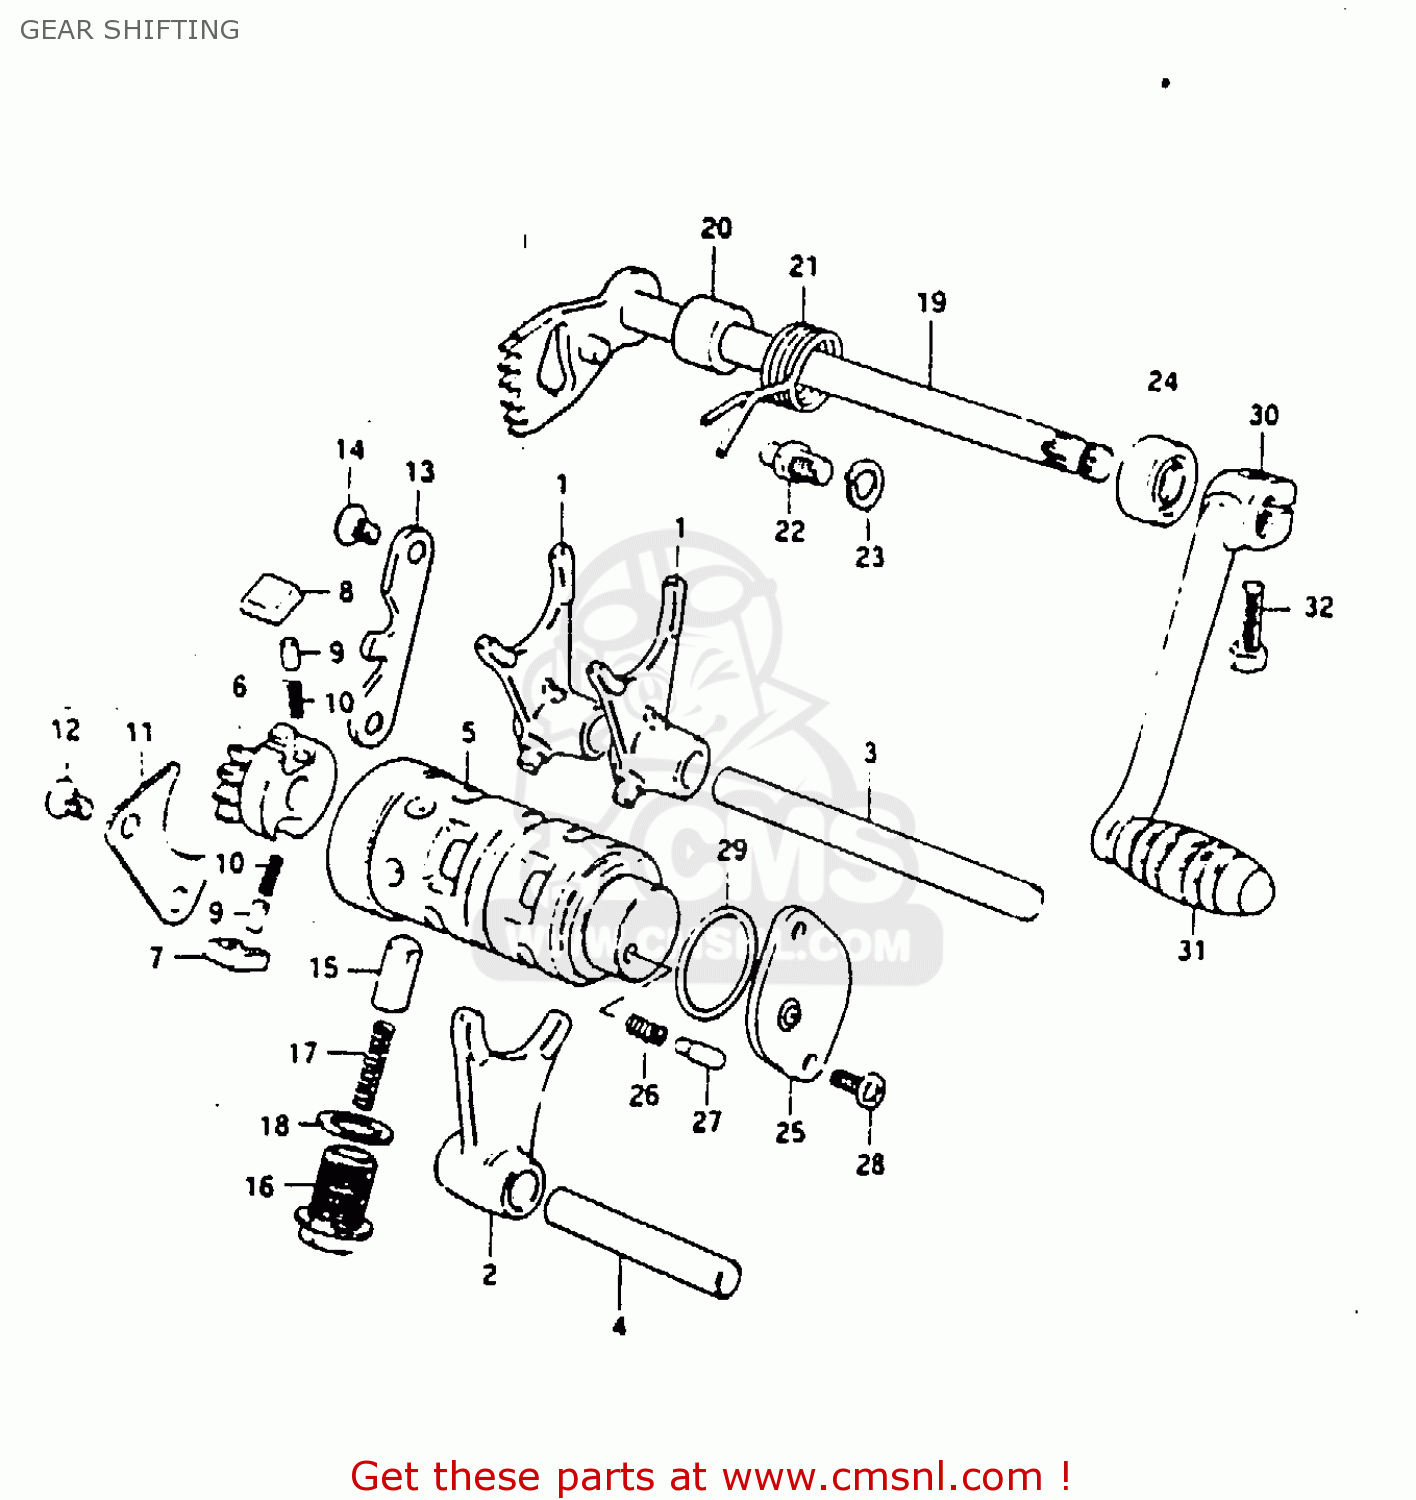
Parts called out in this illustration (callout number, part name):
1	FORK,GEAR SHIFT NO.1
2	FORK,GEAR SHIFT NO.2
3	SHAFT,GEAR SHIFT FORK
4	SHAFT,GEAR SHIFT FORK
5	CAM,GEAR SHIFT
6	GEAR,GEARSHIFT CAM DRIVE
7	PAWL,GEAR SHIFT NO.1
8	PAWL,GEAR SHIFT NO.2
9	PIN(5X8)
10	SPRING
11	LIFTER,GEAR SHIFT POLE
12	SCREW
13	GUIDE,GEAR SHIFT CAM
14	SCREW
15	STOPPER,GEAR SHIFTING
16	BOLT,GEAR SHAFT CAM STOPPER
17	SPRING
18	GASKET(14X19.2X2) (NAS)
19	SHAFT,GEAR SHIFT
20	SPACER(12X20X15.3)
21	SPRING
22	STOPPER,GEAR SHIFT CAM
23	WASHER,LOCK
24	OIL SEAL
25	BODY,GEAR SHIFT SWITCH
26	SPRING
27	PIN(5X15.5)
28	SCREW
29	O-RING (D:2.4 ID:26.2)
30	LEVER ASSY,GEAR SHIFT
31	RUBBER,GEAR SHIFT PEDAL
32	BOLT
